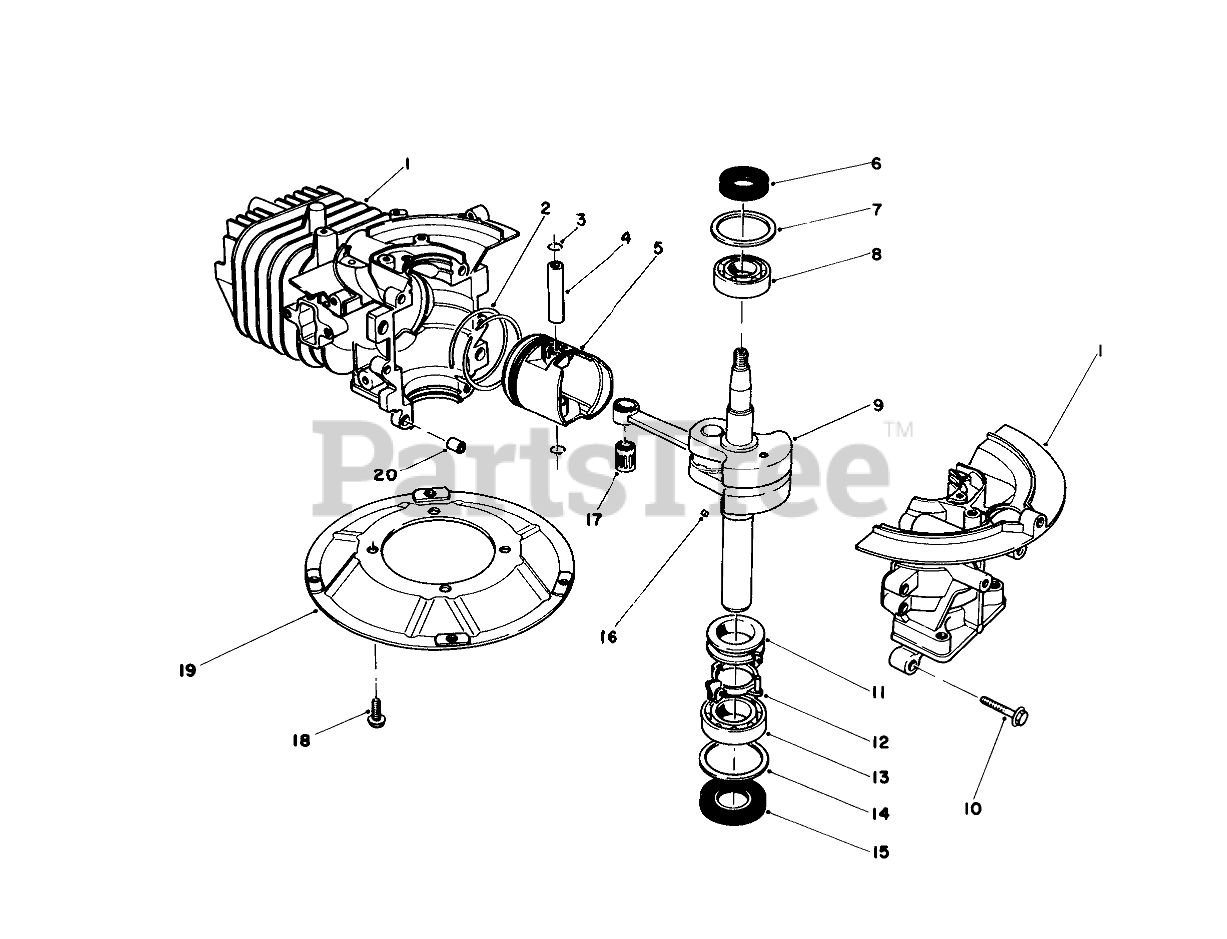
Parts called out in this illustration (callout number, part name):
1	CRANKCASE
2	RING SET
4	PIN-PISTON
5	Piston
6	OIL SEAL
7	WASHER-UPPER
8	BEARING-UPPER
9	Pin-Wrist
11	SPACER
12	BRACKET
13	LOWER BRG
14	WASHER-LOWER
15	SEAL-OIL
17	BEARING
19	PLATE-MOUNTING
